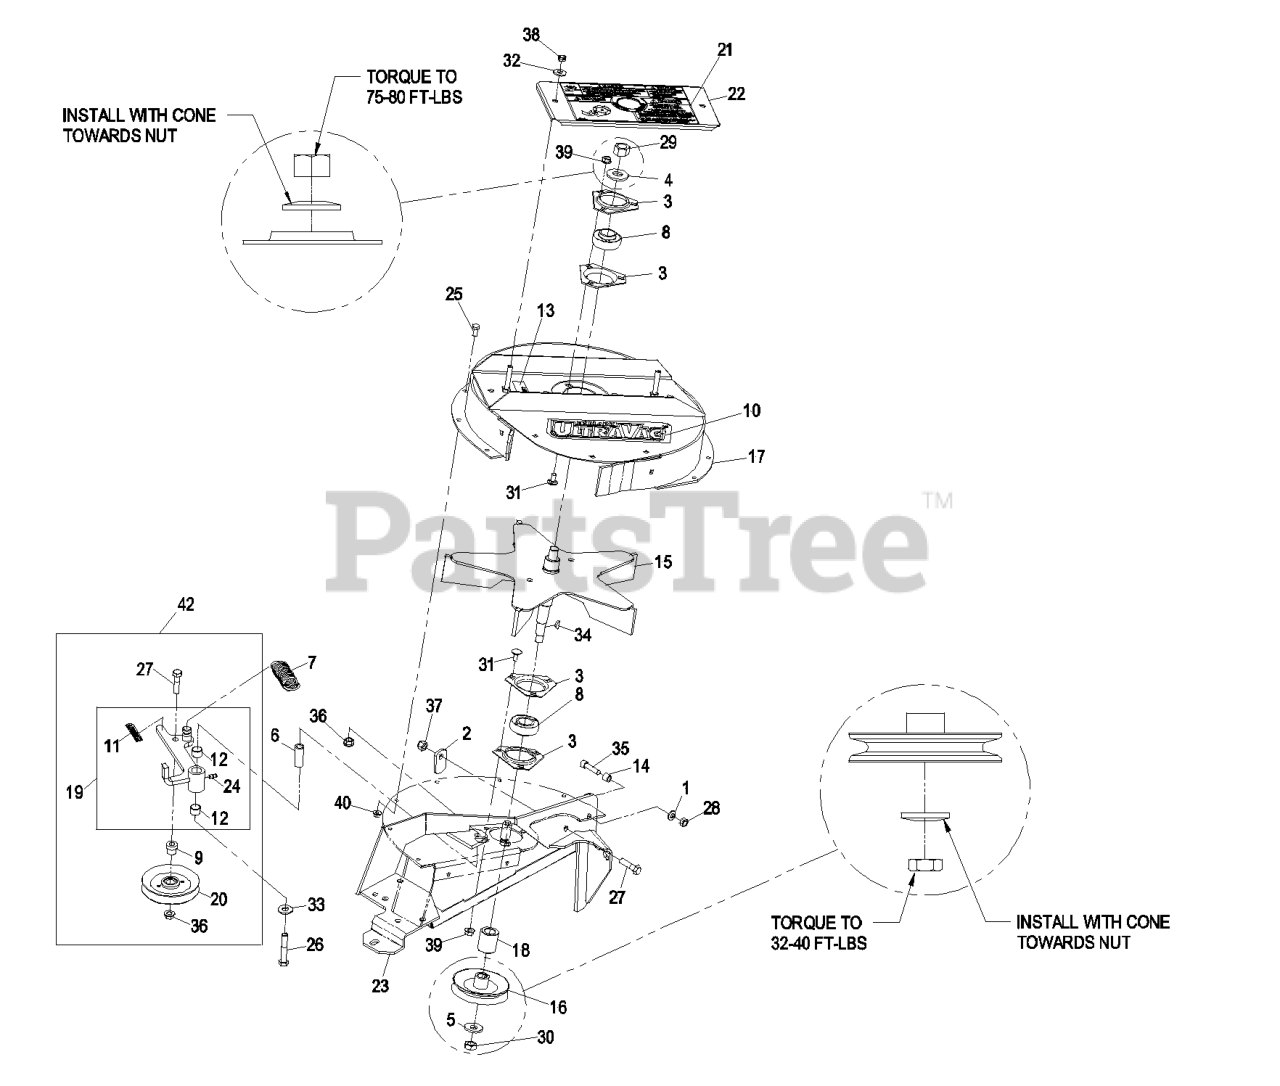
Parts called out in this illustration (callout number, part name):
1	WASHER-SPRING
2	LATCH-CATCHER, GRASS
3	HOUSING-FLANGE
4	WASHER-SPRING
5	WASHER-SPRING
6	BUSHING
7	SPRING-IDLER
8	BEARING
9	HUB,SPACER
10	DECAL, ULTRAVAC
11	DECAL-WARNING
12	BUSHING
13	DECAL-COVER, MISSING
14	BUSHING, LOCATOR
15	IMPELLER
16	SHEAVE
17	ASM, UPPER HSG
19	ASM, IDLER ARM - SERVICE
21	DECAL-WARNING, BLOWER
22	ASM, BEARING COVER
23	WLD,BLOWER MOUNT
24	FITTING-GREASE
25	SCREW-HH
26	SCREW-HH
27	SCREW-HH
28	NUT-HEX
29	NUT-HEX
30	NUT-JAM
31	SCREW-CARR
32	WASHER-FLAT
33	WASHER-FLAT
34	KEY-WOODRUFF
35	SCREW-HSH
36	NUT-HHF, WHIZ
37	NUT-LOCK, NI
38	NUT-LOCK, NI
41	ASM,BLOWER FRUVD
42	Asm, Idler
